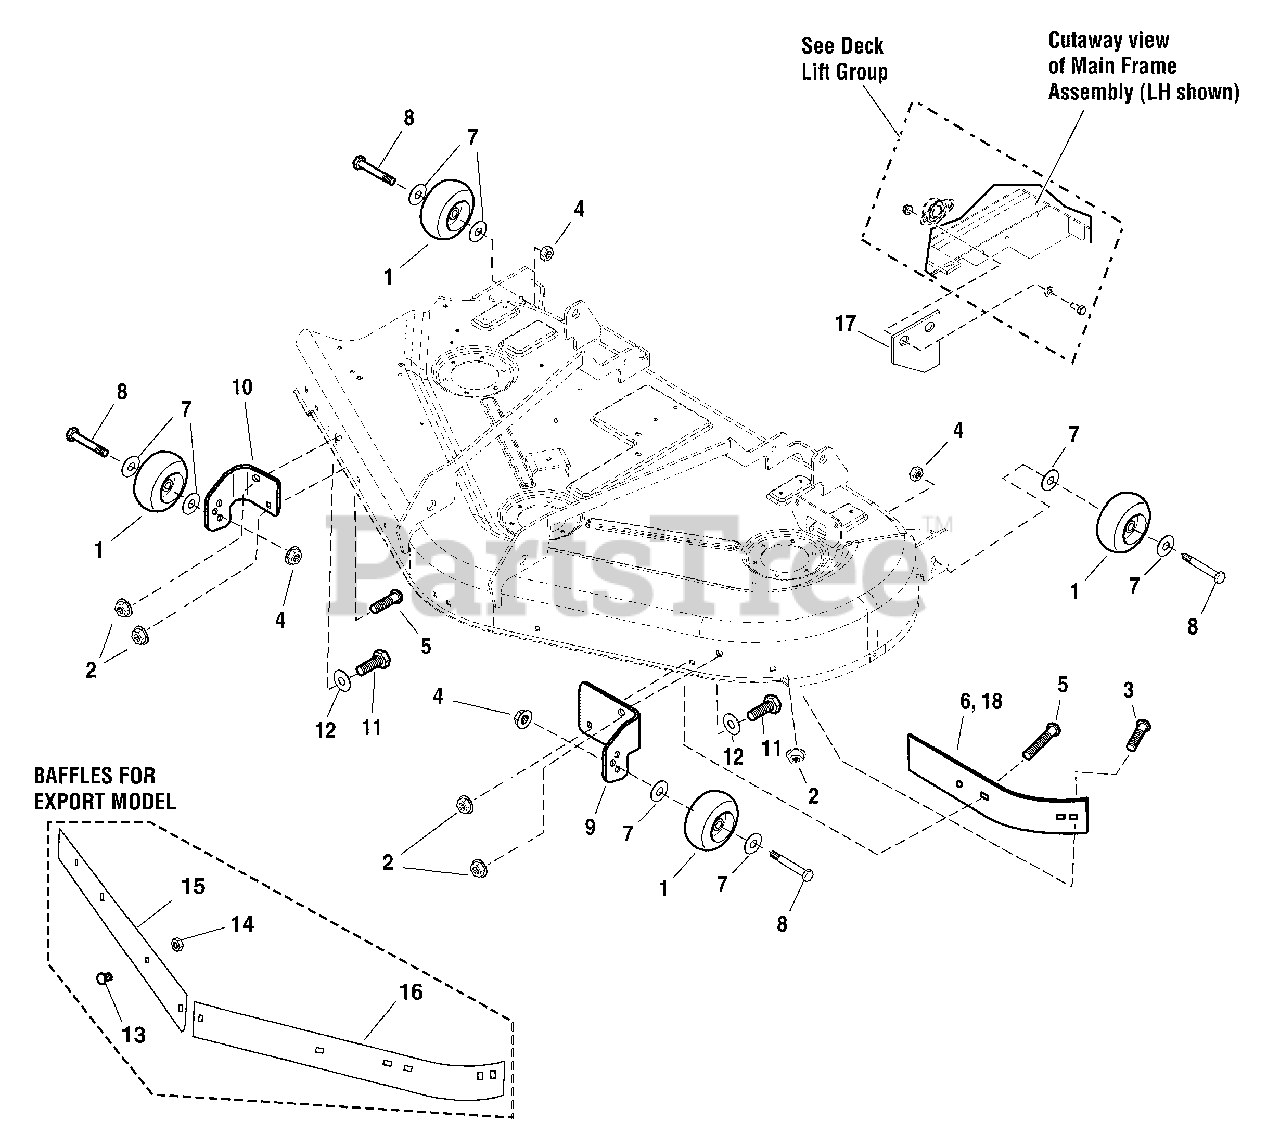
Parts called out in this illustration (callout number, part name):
1	WHEEL, 2.00 WIDE 3.92 DIA 0.531 ID POLY
2	NUT, 5/16-18 HEX NYLOCK FLANGE
3	BOLT, 5/16-18 X 3/4", CARRIAGE
4	NUT, 3/8-16 HEX NYLOCK FLANGE
5	BOLT, 5/16-18 X 1, CARRIAGE
6	SHORT BLOWOUT BAFFLE BLACK
7	WASHER, 0500 (0.51 ID X 0.87 OD X .06 THK) BLK
8	BOLT, WHEEL 3/8-16 X 2.781 .750 THRD YELLOW
9	BRACKET, GUAGE WHEEL, LH
10	BRACKET, GAUGE WHEEL, RH
11	BOLT, 5/16-18 X 1 GD5 YZ
12	WASHER, 5/16" SAE
13	BOLT, 5/16-18 X 3/4", CARRIAGE
14	NUT, 5/16-18 HEX NYLOCK FLANGE
15	BAFFLE, BLOWOUT RH 50" MWR - BLACK
16	BAFFLE, BLOWOUT LH 50" MWR - BLACK
17	PLATE, DECK STOP
18	BAFFLE FRONT 50" MOWER
